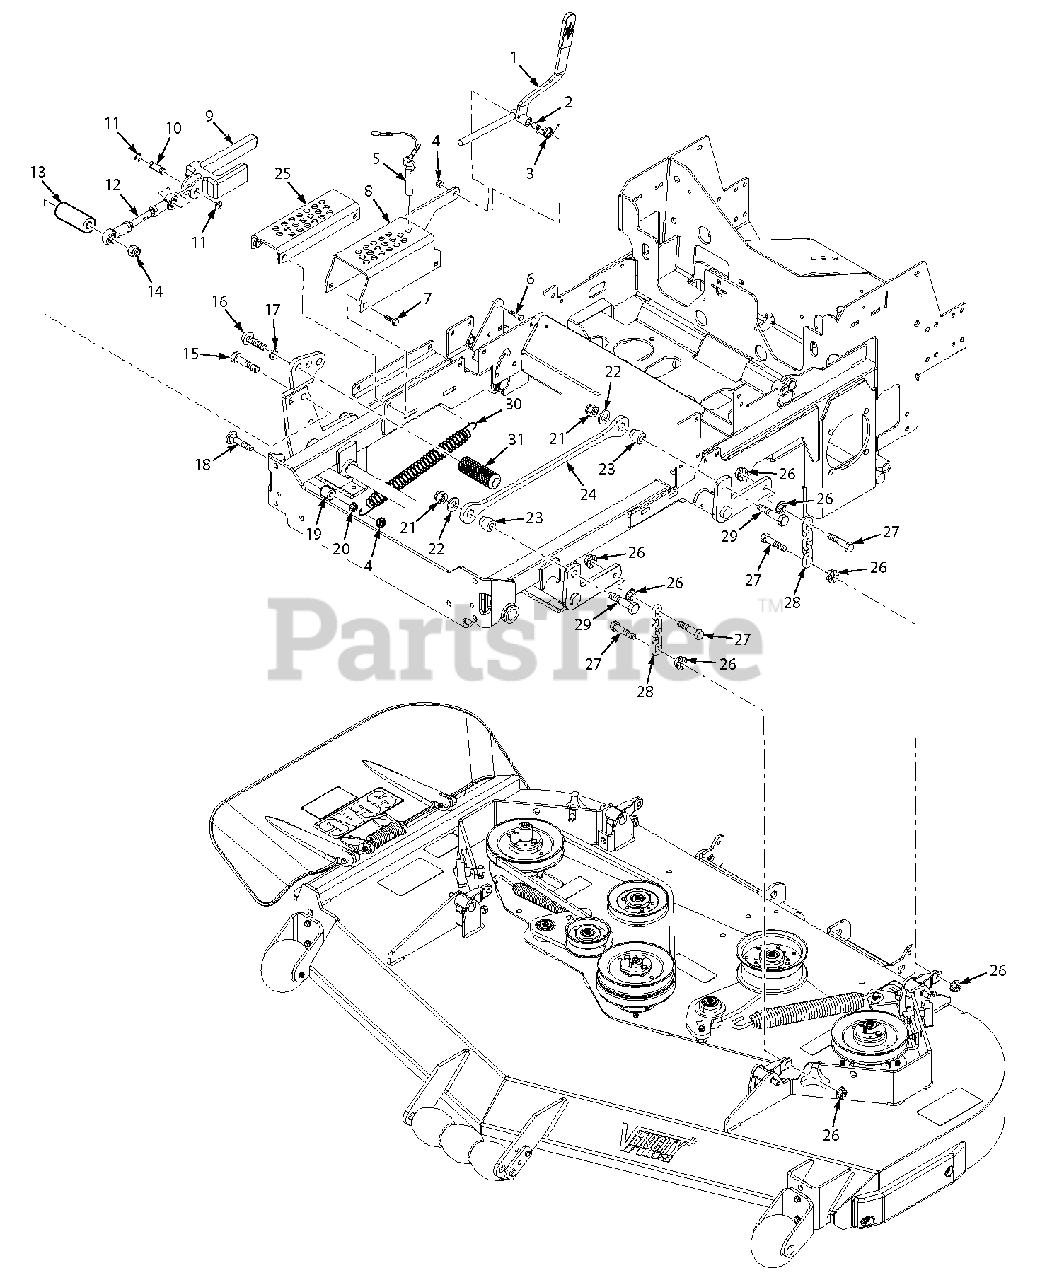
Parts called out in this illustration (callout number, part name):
1	Deck Latch Assembly (Includes Grip)
1	Grip, Deck Latch
2	Spacer, Deck Latch
3	Spring, Torsion - Lever Return
4	Nut, Center Lock 3/8-16
5	Pin Assembly, w/Lanyard
6	Bolt, Hex Head 3/8-16 x 2-1/2"
7	Bolt, Hex Wshr Head 5/16-18 x 1-1/4"
8	Adjustment Bracket, Cutting Height
9	Slide, Height Adjust
10	Pin, Deck Lift
11	Retaining Ring, 1/2" Ext.
12	Linkage Assembly, Deck Lift
13	Spacer, Deck Lift Pedal
14	Nut, Elastic Stop 1/2-13
15	Bolt, Hex Head 1/2-13 x 4"
16	Capscrew, 5/8-11 x 1-1/2"
17	Lockwasher, 5/8" Spring
18	Bolt, Carriage 3/8-16 x 2-1/2"
19	Spacer
20	Nut, Serrated Flange 3/8-16
21	Nut, Elastic Stop 1/2-13
22	Flatwasher, 1/2-.562 x 1.375 x .109
23	Pivot, Deck Link
24	Link, Decklift
25	Adjustment Bracket, Lower Cut Height
26	Nut, Serrated Flange 3/8-16
27	Bolt, Hex Head 3/8-16 x 1-1/2"
28	Chain
29	Bolt, Hex Head 1/2-13 x 2-1/4"
30	Spring, Decklift
31	Foot Pedal, Height Adjustment
